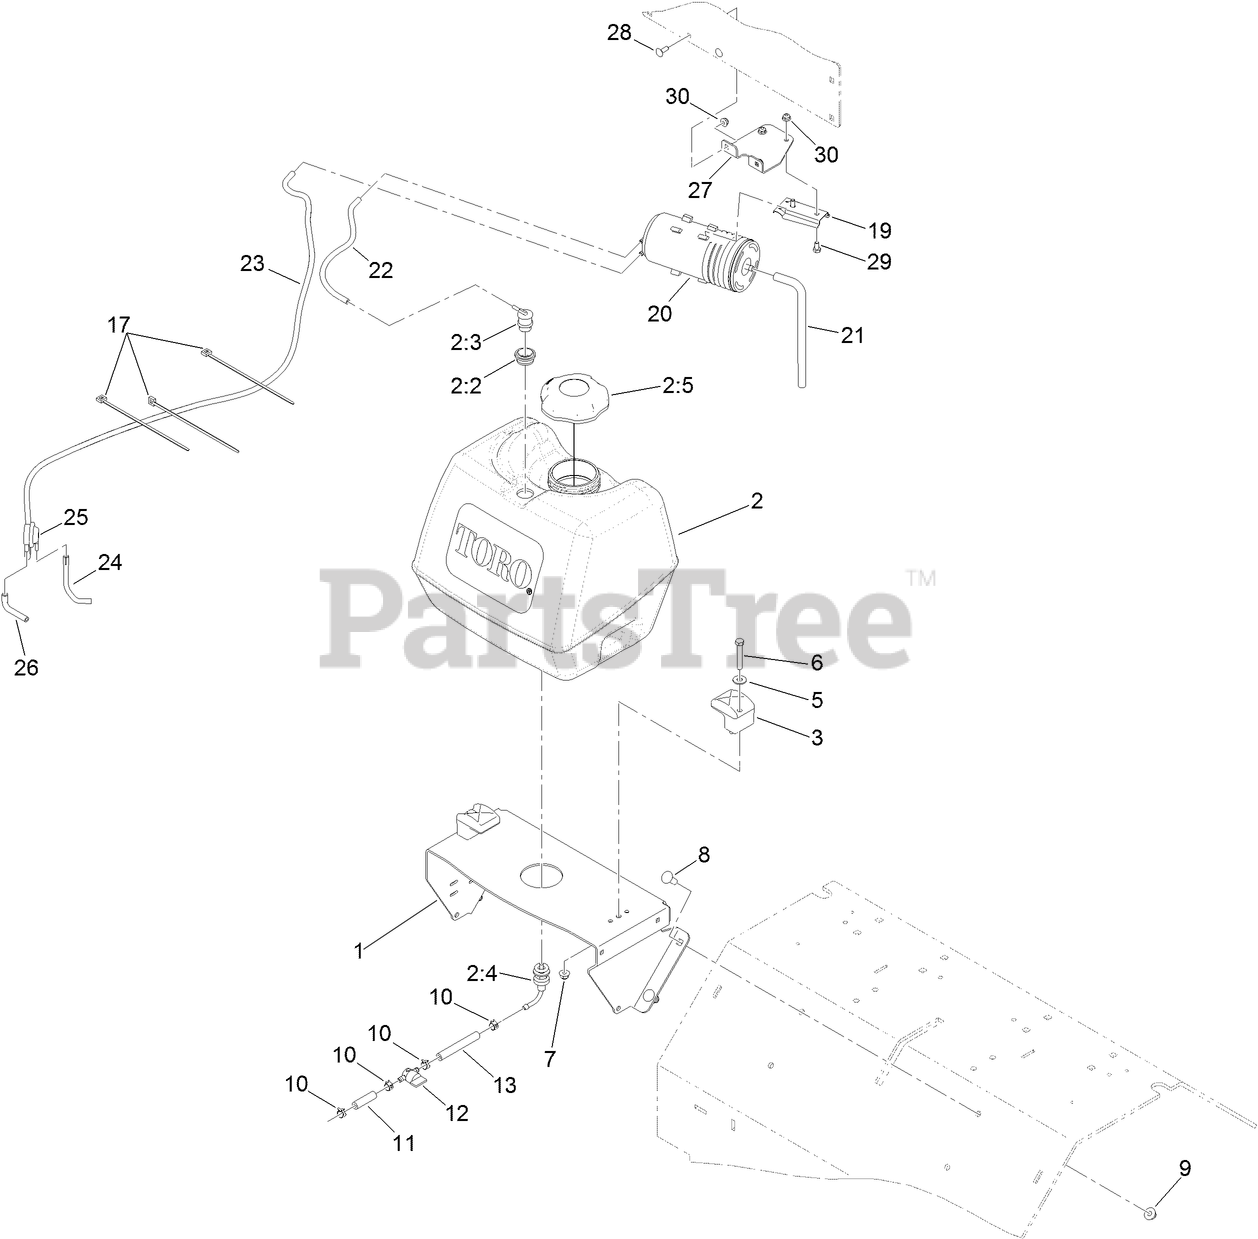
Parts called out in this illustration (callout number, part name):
1	SUPPORT-TANK, FUEL
2	FUEL TANK ASM
2:2	GROMMET
2:3	VALVE-VENT, FUEL
2:4	FITTING-FUEL, BULKHEAD
2:5	CAP-FUEL, RATCHETING
5	WASHER-FLAT
6	SCREW-HH
7	NUT-HF, NI
8	SCREW-CARR
9	NUT-HF, NI
10	CLAMP-HOSE
11	HOSE-FUEL
12	VALVE-FUEL
13	HOSE-FUEL
17	TIE-PLASTIC
19	BRACKET-CANISTER, CARBON
20	CANISTER-CARBON, 800CC
21	HOSE-VENT, CANISTER
22	HOSE-EMISSIONS
23	HOSE-VENT, FORMED
24	HOSE-VENT, FORMED
25	VALVE-CONTROL, VACUUM
26	HOSE-VENT, FORMED
27	BRACKET-MOUNTING, CANISTER
28	BOLT-CARR
29	SCREW-HH
30	NUT-HF
